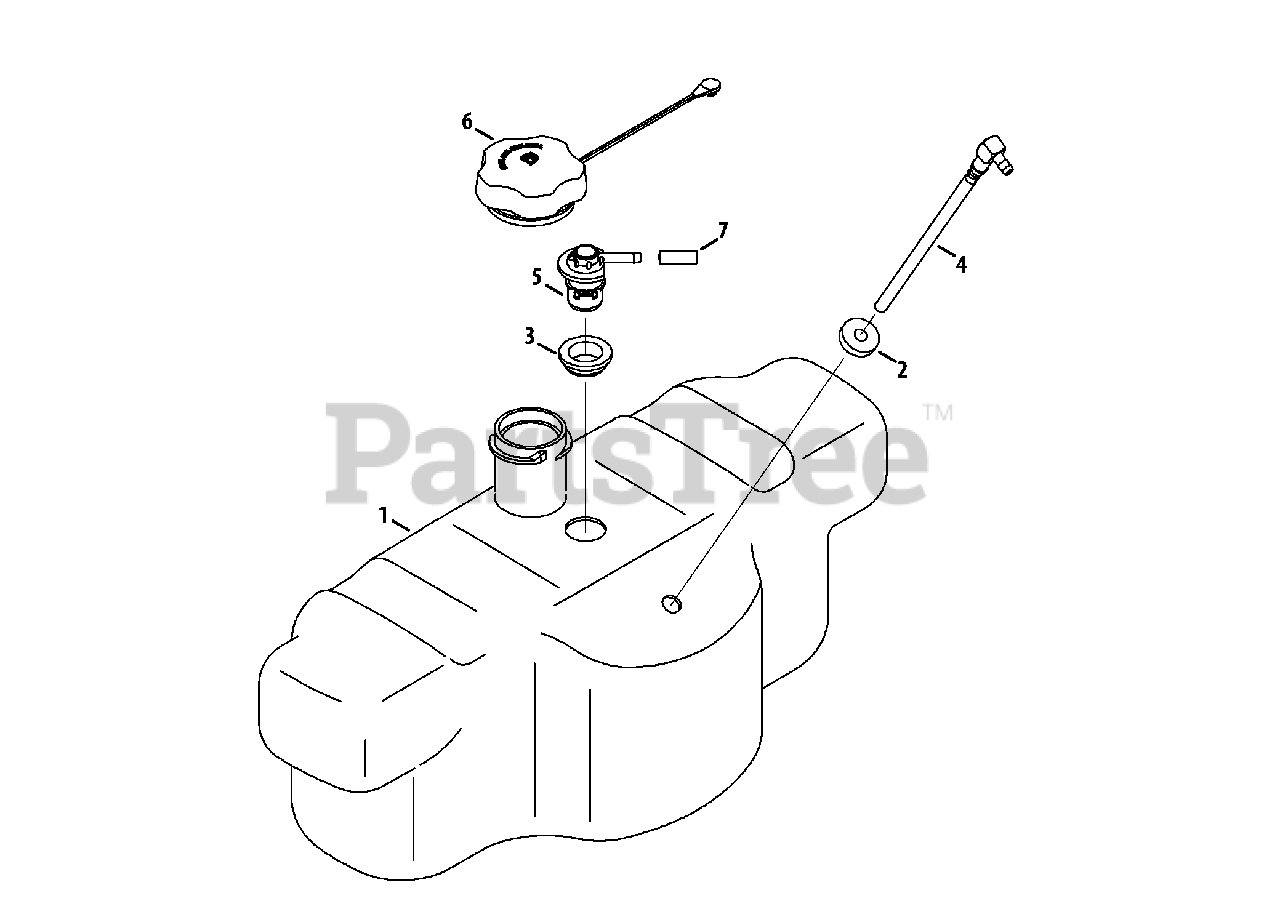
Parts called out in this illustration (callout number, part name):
1	Fuel Tank
2	Fuel Tank Bushing
3	Rubber Grommet
4	Fuel Pickup Fitting
5	Rollover Valve
